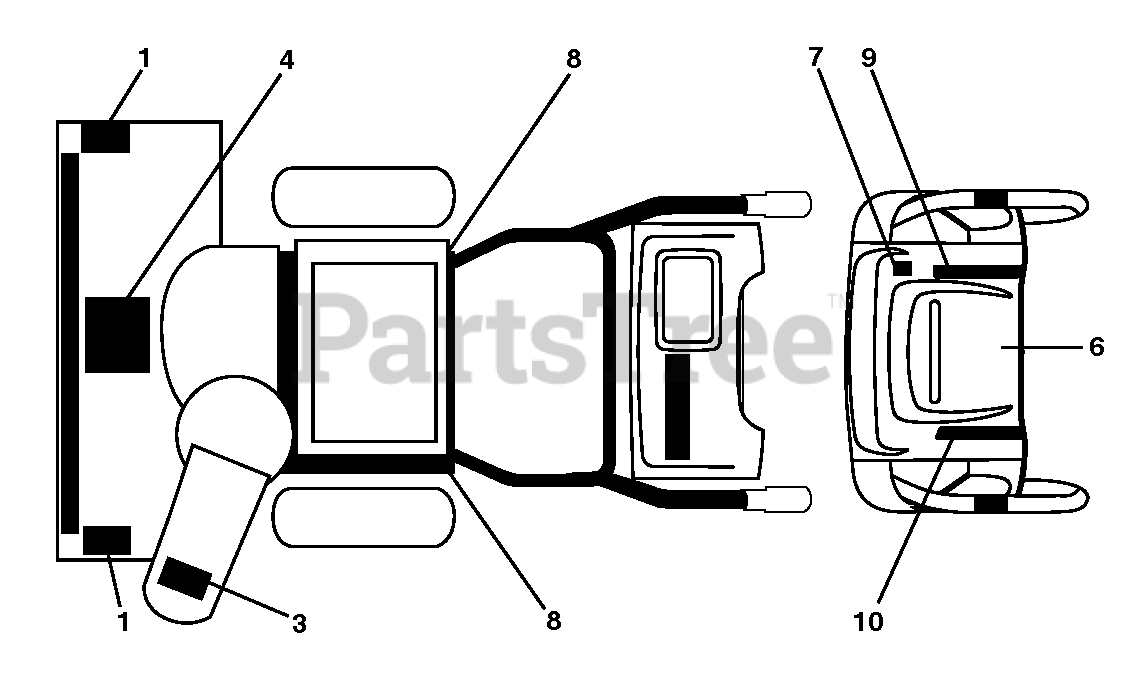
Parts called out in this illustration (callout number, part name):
1	DECAL.AUGER.SAFETY.
3	DECAL.CHUTE.SAFETY.
4	DECAL.AUGER."
7	DECAL.CONSOLE.HAND.WARMER
8	DECAL.BELT.GUARD.
9	DECAL CONSOLE DECAL DECAL.SNOW
10	DECAL CONSOLE DECAL DECAL.SNOW
